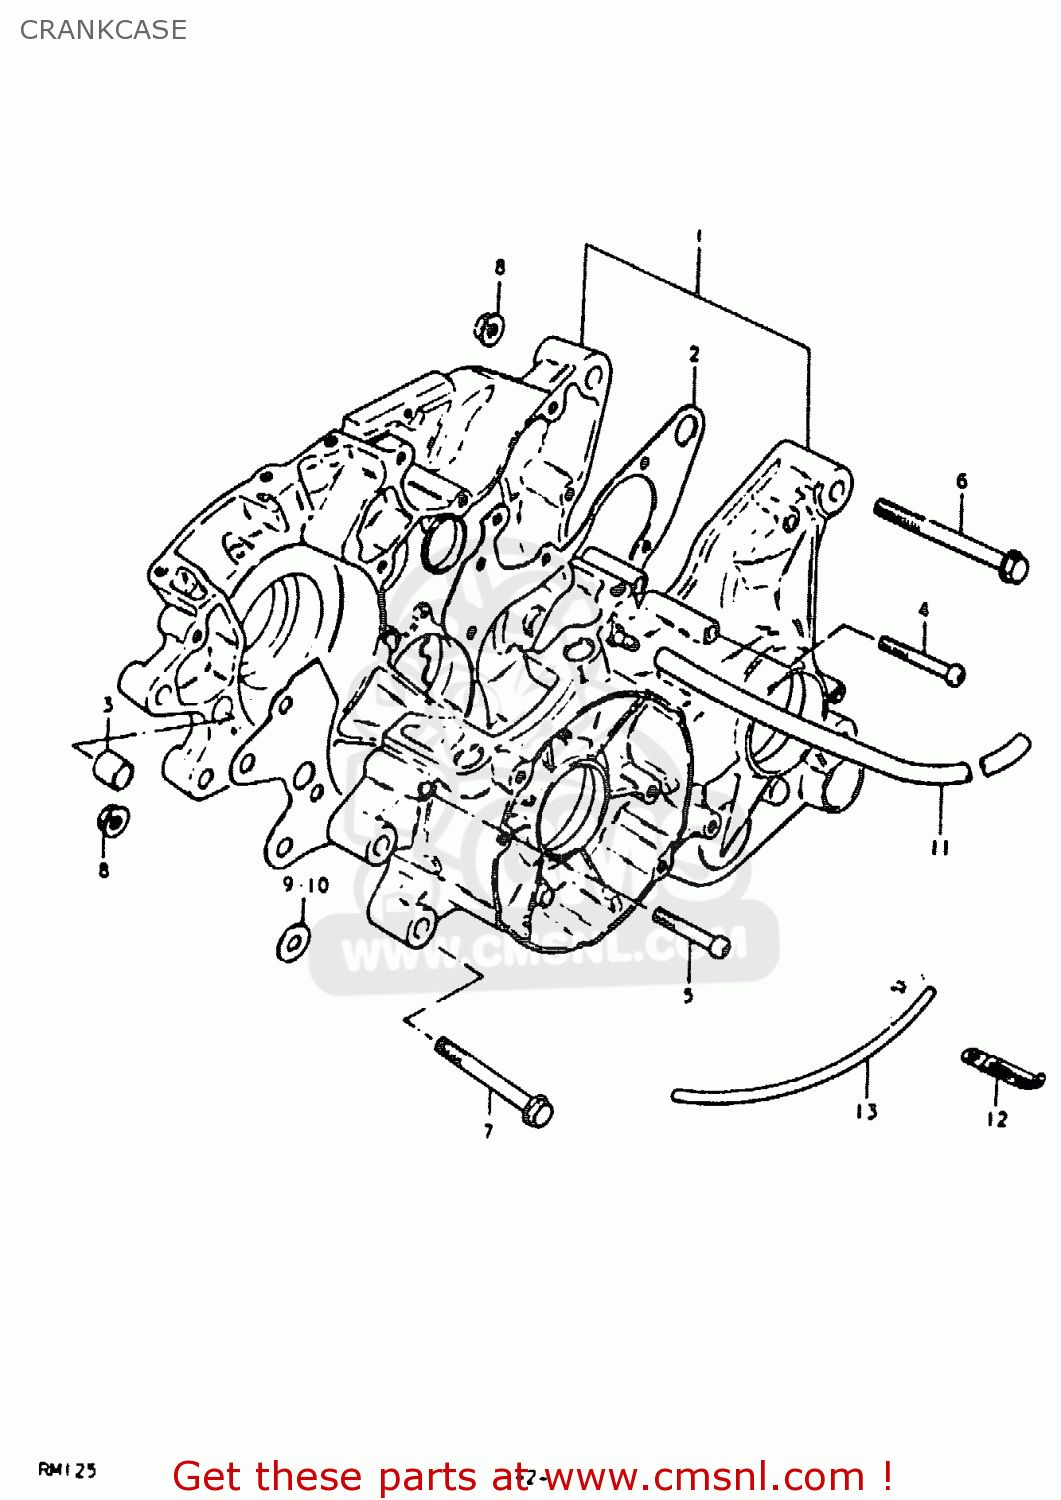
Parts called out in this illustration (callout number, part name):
1	CRANKCASE SET
2	GASKET,CRANKCASE (MCA)
3	PIN
4	SCREW
5	SCREW (6X45)
6	BOLT 8X90
7	BOLT(8X67)
8	NUT
9	WASHER
10	WASHER
11	HOSE
12	CLAMP
13	HOSE
